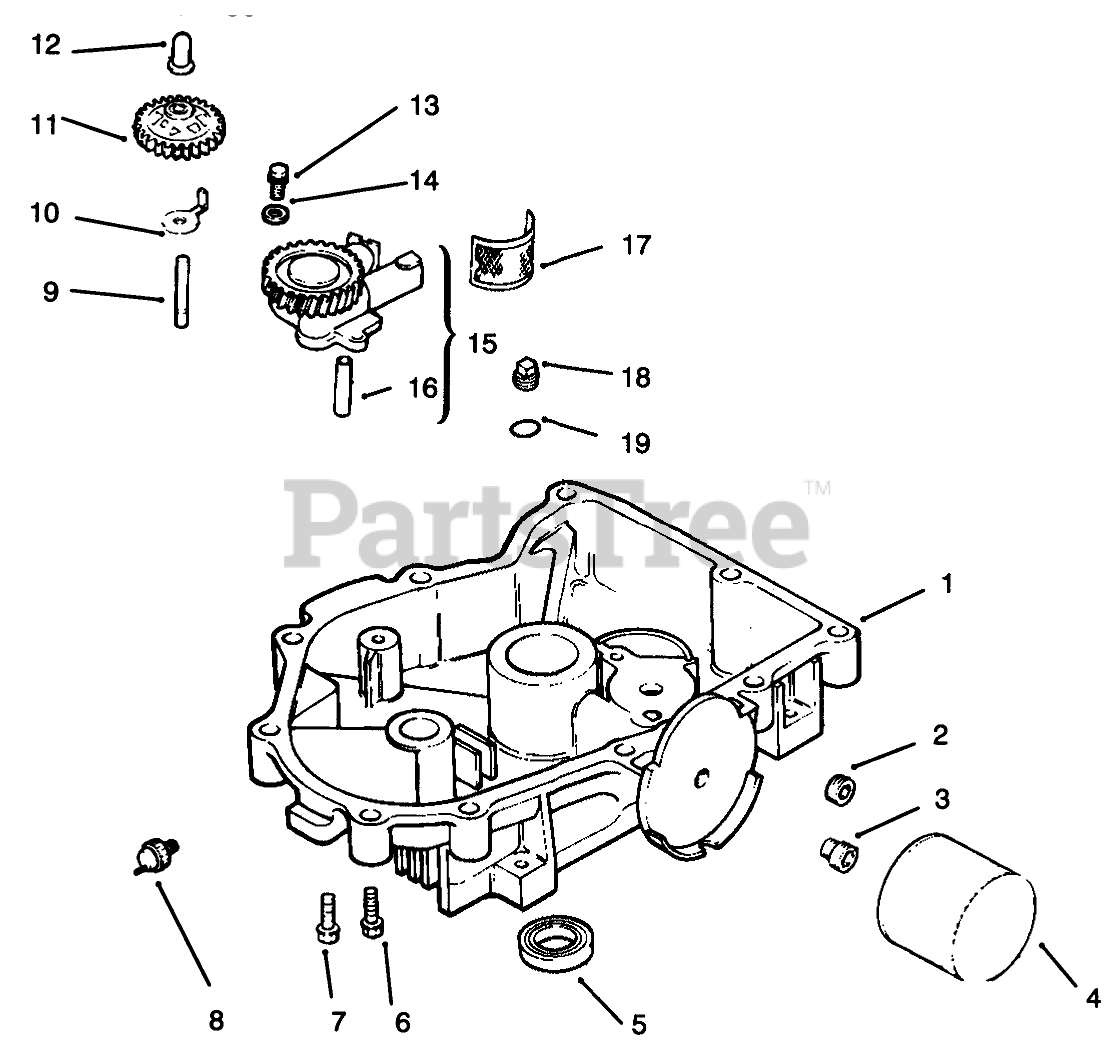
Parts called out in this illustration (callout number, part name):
1	Oil Pan (Only On: 72103)
2	Plug-HS 3/8 NPTF (Only On: 72103)
3	Nipple-Oil Filter (Only On: 72103)
4	Filter-Oil (Only On: 72103)
5	Seal-Oil (Only On: 72103)
6	Screw M8x1.25x45 (Only On: 72103)
7	Screw M8x1.25x45 (Only On: 72103)
8	Switch-Oil Pressure (Only On: 72103)
9	Shaft-Governor Gear (Only On: 72103)
10	Tab-Locking (Only On: 72103)
11	Governor Gear ASM (Only On: 72103)
12	Pin-Governor Regulating (Only On: 72103)
13	Screw-Valve Cover (Only On: 72103)
14	Washer-Governor (Only On: 72103)
15	Oil Pump ASM INCL 16 (Only On: 72103)
16	Tube-Oil Pickup (Only On: 72103)
17	Screen-Oil Pickup (Only On: 72103)
18	Plug-SH 3/8 NPTF (Only On: 72103)
19	O Ring (Only On: 72103)
